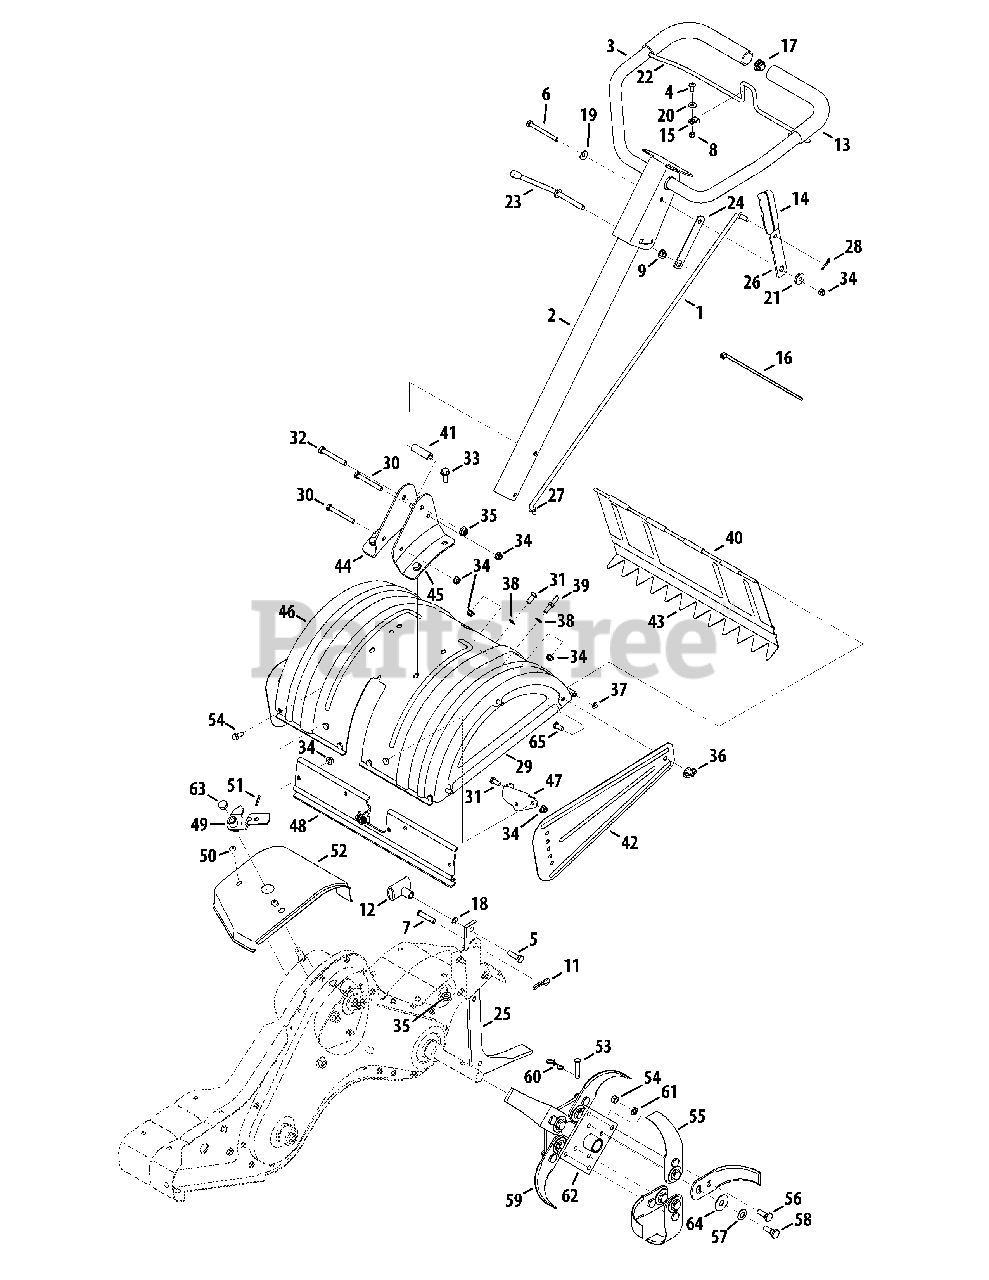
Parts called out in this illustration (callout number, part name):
1	Shift Rod
2	Lower Handle Ass’y
3	Upper Handle Ass’y
4	Screw 1/4-20 x .625
5	Hex Bolt 3/8-16 x 1.25
6	Hex Bolt 5/16-18 x 3.25
7	Clevis Pin 3/8 Dia
8	Flanged Lock Nut 1/4-20 Gr. 5
9	Hex Flange Nut 3/8-24 Thd.
10	Hex Ins. L-Nut 5/16-18
11	Hairpin
12	Small "T" Knob
13	Grip (2 req’d)
15	Battery Clamp
16	Cable Tie
17	Vinyl End Plug
18	Flat Washer .385 ID x .62 OD x .033
19	Bell. Washer .345 ID x .88 OD x .06
20	Flat Washer .260 x .720 x .060
21	Shoulder Spacer
22	Bail Clutch
23	Handle Adj. Crank
24	Bracket Hex Nut Retainer
25	Depth Bar
26	Shift Lever Rod
27	Rubber Washer .33 ID x .125
28	Int. Cotter Pin 5/16 Dia.
29	Tine Shield Cover Ass’y
30	Hex Scr 5/16-18 x 2.75
31	Hex Bolt 5/16-18 x .75" Lg. Gr. 5
32	Hex Screw 3/8-16 x 2.75" Lg.
33	Carriage Bolt 3/8-16 x .875" Lg.
34	Flanged Lock Nut 5/16-18 Gr. 5
35	Flange Lock-Nut 3/8-16 Gr. F Nylon
36	Wing Nut
37	Push Cap
38	Flat Washer .34 ID x .62 OD x .03
39	Hex Screw 5/16-18 x .75
40	Tiller Flap Rod
41	Spacer .322 ID x .47 OD
42	Side Shield
43	Rear Tine Shield
44	RHHandle Brkt.
45	LH Handle Brkt.
46	Tine Shield
47	Tine Shield Brkt.
48	Shoulder Spacer
49	Shift Crank Ass’y
50	Hex Hd TT Scr. 1/4 x .625" Lg.
51	Spring Pin Roll 3/16 Dia.
52	Shift Cover
53	Clevis Pin 3/8 Dia
54	Hex L-Nut 3/8-24 (Grade 5)
55	13" Dia. Articulating Tine
56	Shld. Scr. 1/2 Dia. x .175
57	Belleville washer .505 ID x 1.00 OD x .0
58	Shld. Bolt 1/2" Dia. x .320
59	Tine Adapter Assembly, 18"
60	Bow Tie Cotter Pin
61	L-Wash 3/8 ID
62	Tine Adapter Plate
64	Stud, 5/16-18 x .75
